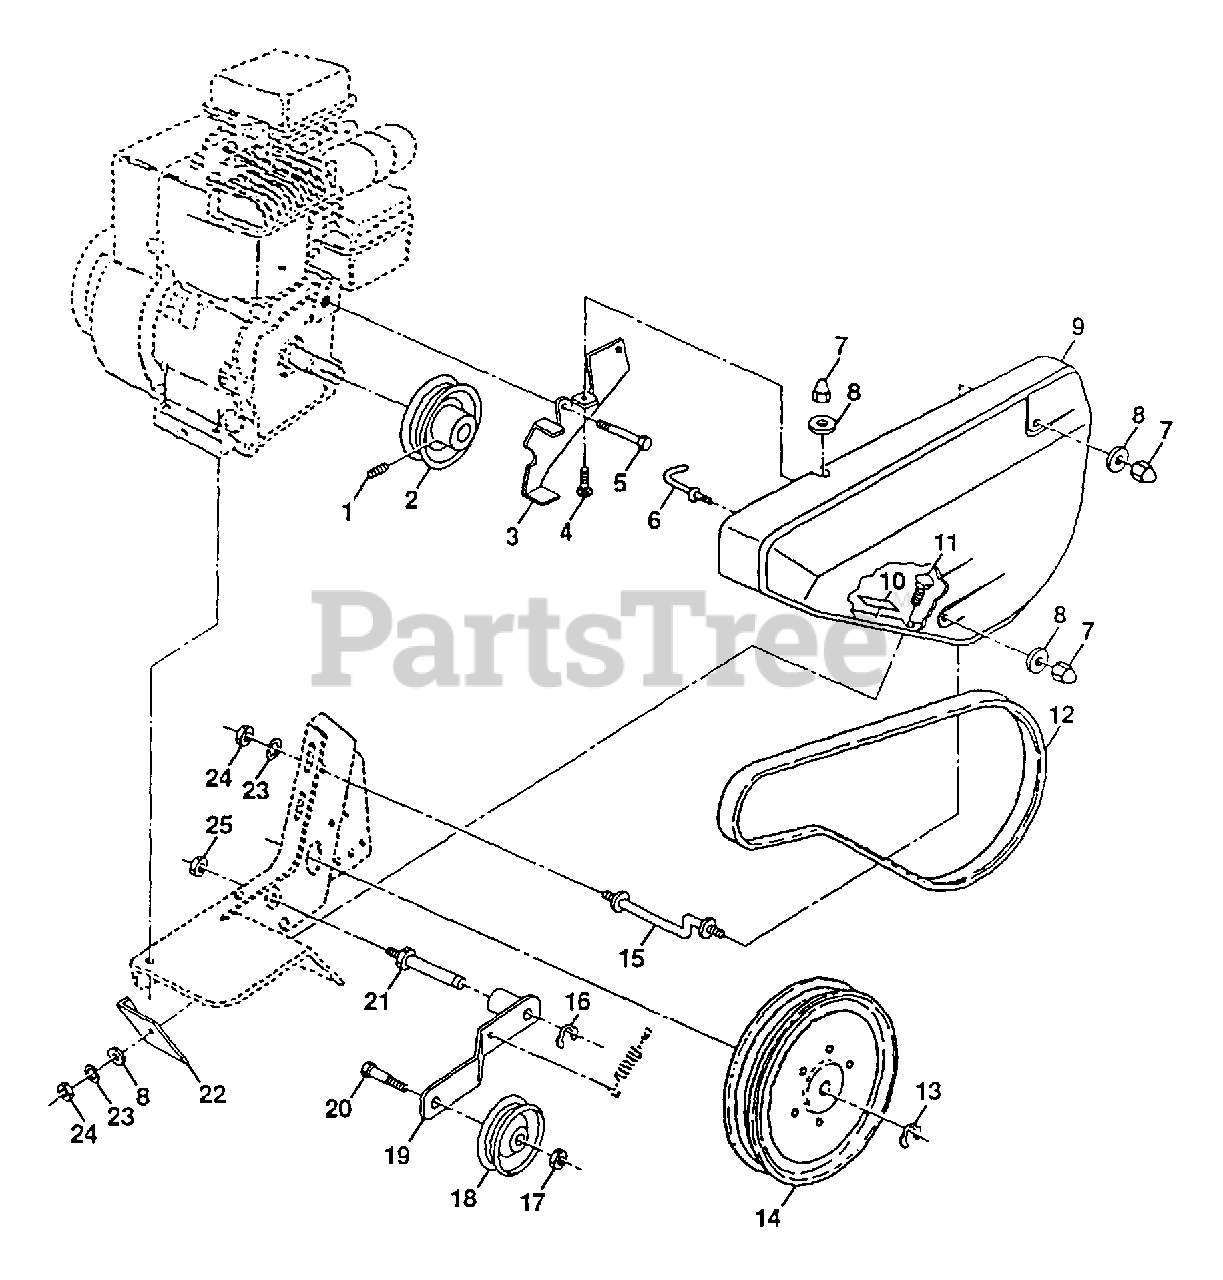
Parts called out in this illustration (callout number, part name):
1	Screw, Set, Forged Socket, Headless 5/16-18 x 3/8
2	Pulley, Engine (AYP part number)
3	Bracket Assembly, Guard, Belt
4	Bolt, Carriage 1/4-20 x 1/2
5	Bolt, Hex 1/2-20 x 3/4
6	Keeper, Belt, Transmission Pulley
7	Nut, Cap 1/4-20
8	Washer 9/32 x 5/8 x 16 Ga.
9	Guard, Belt
10	Pad, Idler
11	Bolt, Carriage 1/4-20 x 3/4
12	V-Belt
13	Ring, Retainer (AYP part number)
14	Pulley, Transmission
15	Bolt, Belt Guard
16	Ring, Klip
17	Nut, Hex, Jam 3/8-16
18	Pulley, Idler
19	Idler Arm Assembly
20	Bolt, Hex 3/8-16 x 1-1/4
21	Shaft, Idler Arm (AYP part number)
22	Shield, Dirt
23	Washer, Lock 1/4
24	Nut, Hex 1/4-20
25	Nut, Hex, Jam 5/16-18
